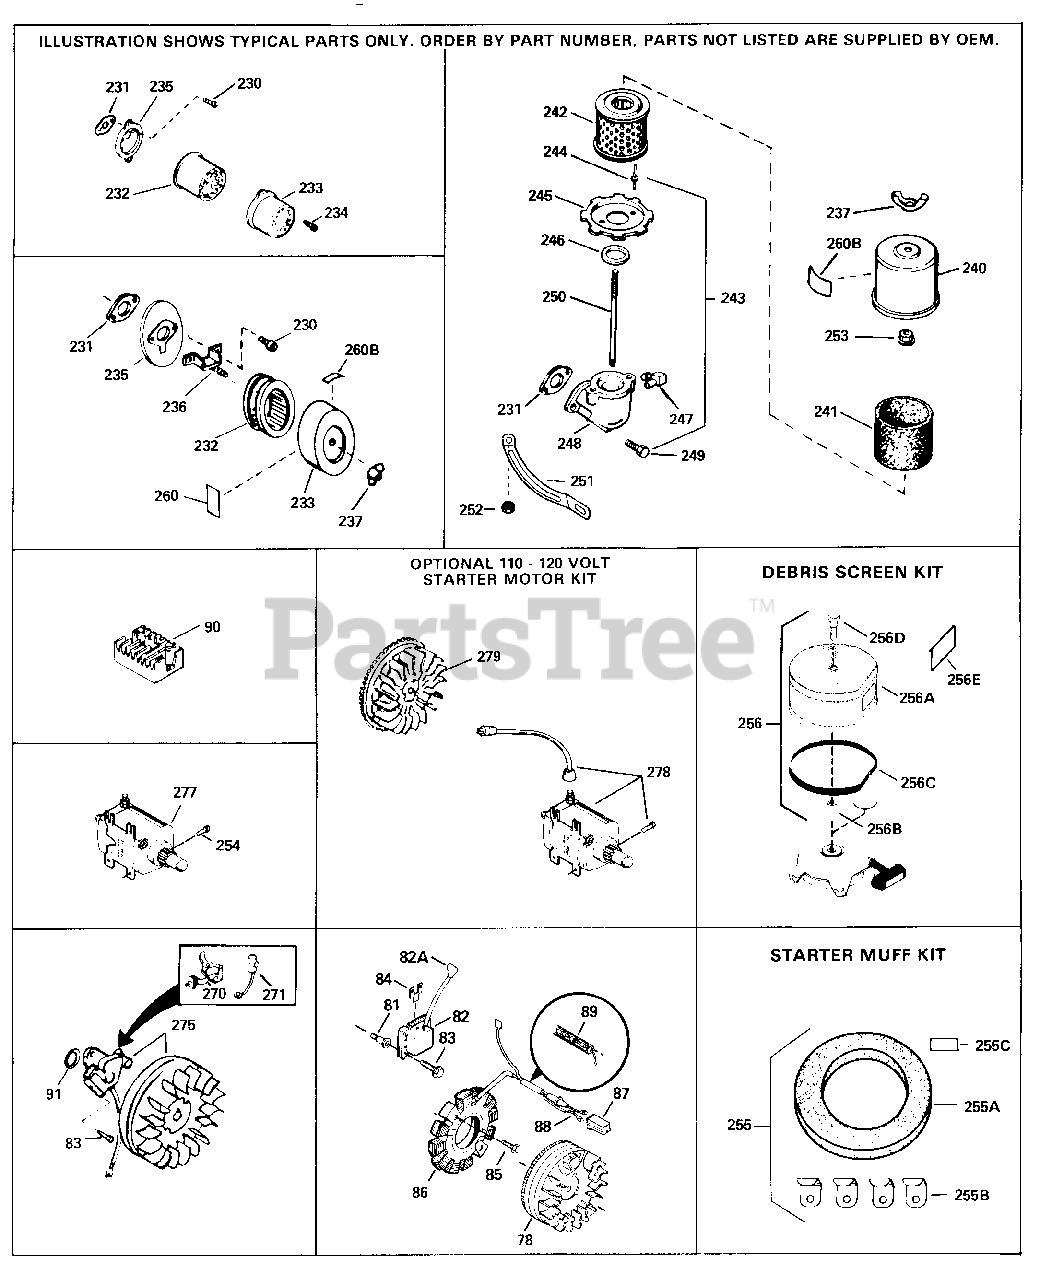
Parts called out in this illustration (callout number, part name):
82A	Spark Plug Cover
82A	Cover, Spark plug (Use as required)
83	Screw, 1/4-20 x 5/8"
91	Gasket, Stator
98	Screw, 5/16-18 x 1-1/2" Use as requir ed, but do notuse No. 650691 washer.
98	Screw, 5/16-18 x 1-3/4" Use as requir ed
98	Screw, 5/16-18 x 1-5/8" (Use as requi red) (Can use No. 6021A but discard N o. 650691 washer.)
230	Screw, 10-32 x 1/2"
231	* Gasket, Air cleaner
232	Air Filter (Paper) also available in Packaged Part #740027B
233	Cover, Air cleaner
235	Bracket, Air cleaner
236	Bracket, Air cleaner
237	Nut, Wing, 1/4-20
255	Starter Muff Kit (Incl. 255A, 255B, & 255C) Can be used on HM70 with diec ast starter
255A	Air Cleaner, Starter Can be used on H M70 with diecast starter
255B	Bracket, Starter air cleaner Can be u sed on HM70 with diecast starter
255C	Instruction Decal Can be used on HM70 with diecast starter.
256	Debris Screen Kit (Incl. 256A thru 25 6E) Can be used on HM70 with sta mped steel recoil starter
256A	Debris Screen Can be used on HM70 wit h stamped steel recoil starter
256B	Spacer, Screen Can be used on HM70 wi th stamped steel recoil starter
256C	Seal, Screen Can be used on HM70 with stamped steel recoil starter
256D	Screw, 5/16-18 x 1-5/8" Can be used o n HM70 with stamped steel recoil star ter
256E	Instruction Decal Can be used on HM70 with stamped steel recoil starter.
270	Breaker Points (also available in Pac kaged Part #740037B)
271	Condenser (also available in Packaged Part #740037B)
275	Magneto NOTE: The complete magneto i s not available as an assembly. The magneto number is shown for reference purposes only. Order component part s individually, as shown in parts lis t. (Refer to Division 5, Section B, p age 28 for breakdown)
278	Starter Motor Kit (110-120 Volt) This 110-120 volt starter motor kit may h ave been added to this engine. It can be added only if cylinder hasdrilled and tapped starter mounting bosses a nd a ring gear flywheel has been adde d (see #279). Refer to s
279	Flywheel (Ring gear flywheel required on engine using 110-120 Volt starter motor kits listed above.) (Use on Std . point ignition)
279	Flywheel (Minimum ring gear flywheel required on engine using 110-120 Volt starter motor kits listed above.) (U se on Solid State ignition)
